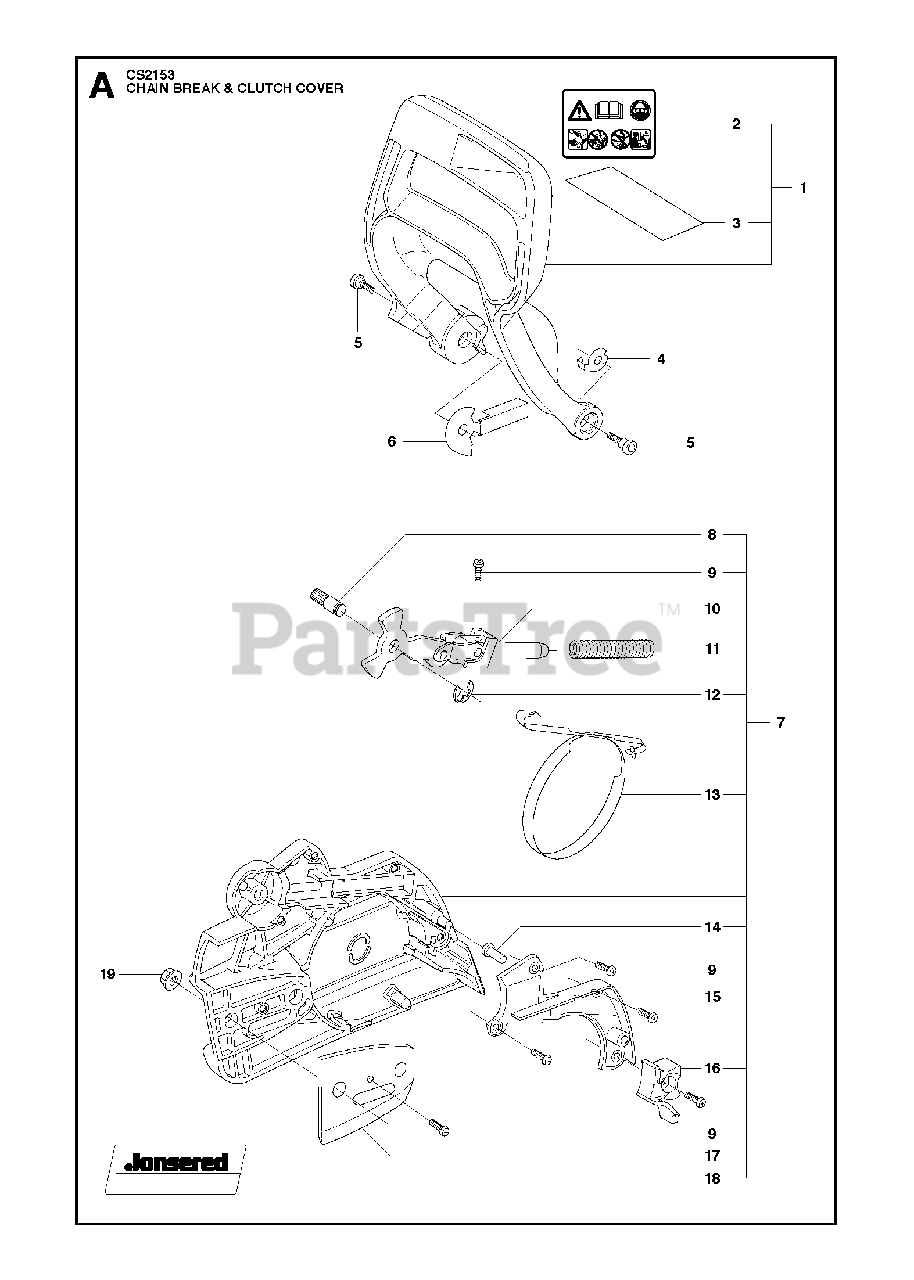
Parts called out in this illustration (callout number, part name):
1	HAND GUARD
2	DECAL
3	PROTECTOR
6	PROTECTOR
7	CHAIN BRAKE
8	PIN
9	SCREW
10	JOINT
11	SPRING
12	E-RING 4
13	BRAKE BAND
14	SLEEVE
15	COVER
16	PROTECTOR
17	PLATE
18	DECAL
19	NUT M8 FLANGE
